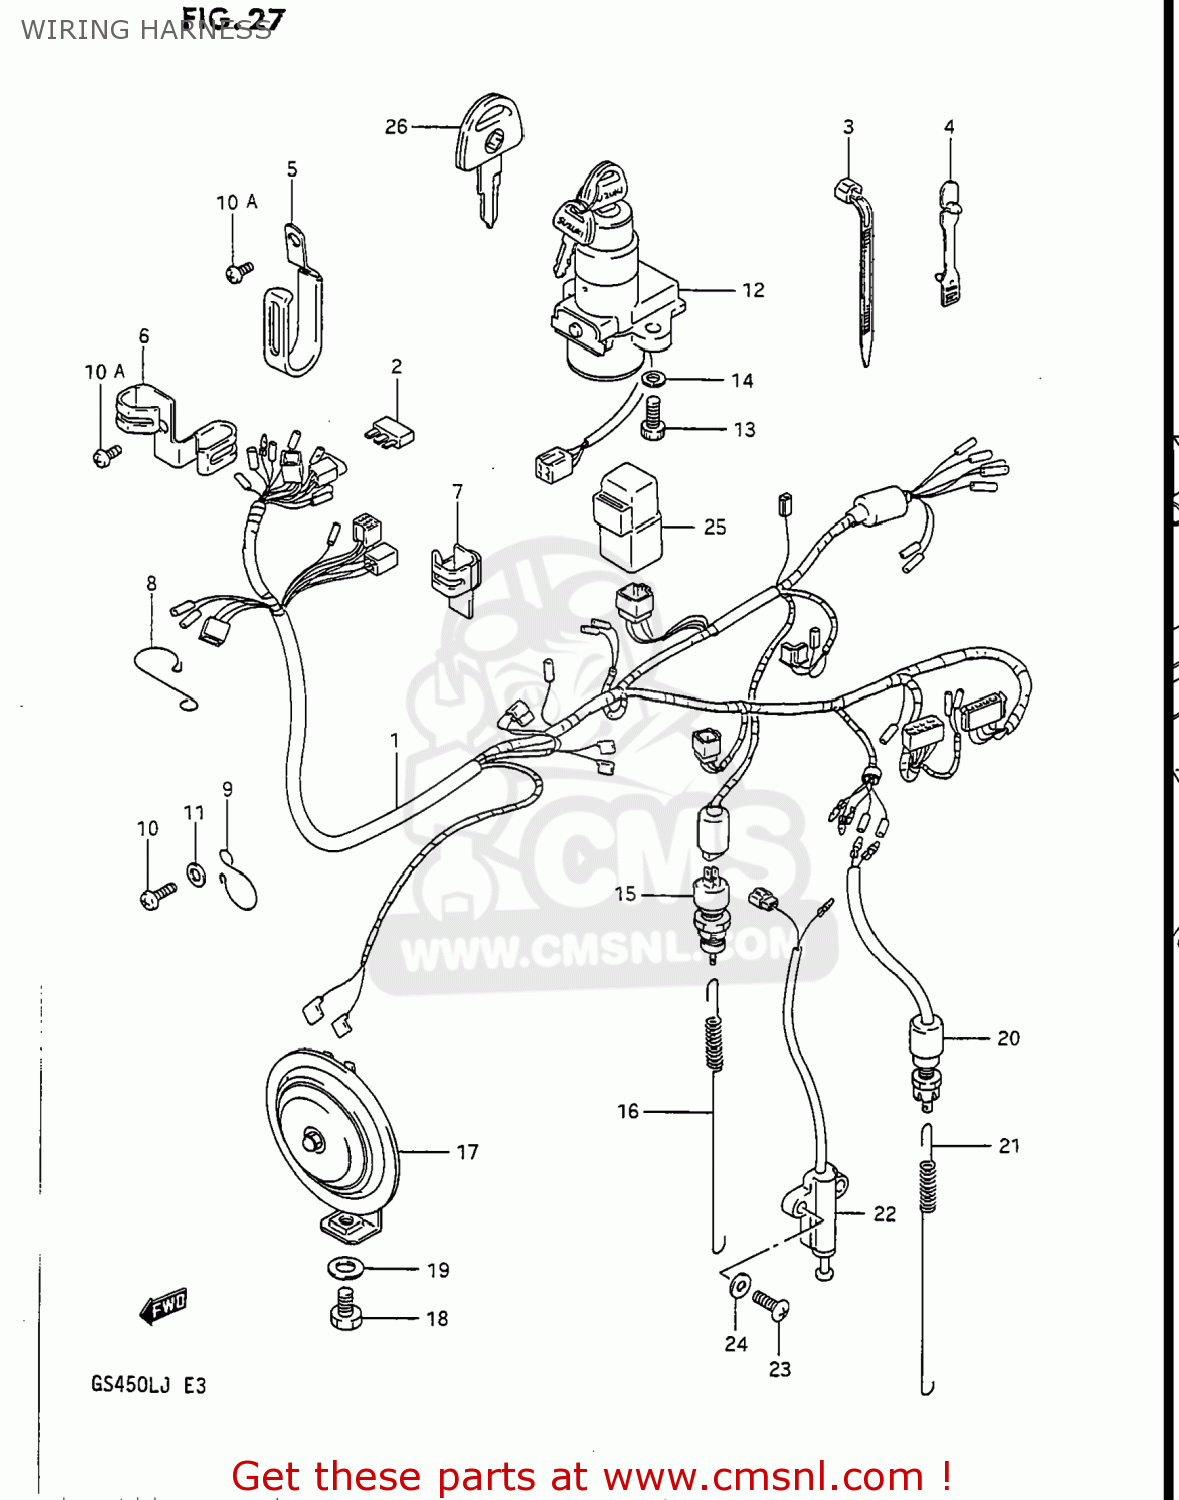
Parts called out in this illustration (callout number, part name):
1	HARNESS,WIRING
2	DIODE(STANLEY DE8804)
3	CLAMP(L:125)
4	CLAMP,L:88
5	CLAMP,WIRING HARNESS
6	CLAMP,WIRING HARNESS
7	CLAMP,WIRING HARNESS
8	CLIP,WIRING HARNESS
9	CLIP,WIRING HARNESS
10	SCREW
10A	SCREW
11	WASHER
12	SWITCH ASSY,IGNITION
13	BOLT
14	WASHER,LOCK
15	SWITCH ASSY,STOP LAMP
16	SPRING
17	HORN ASSEMBLY
18	BOLT
19	WASHER
20	SWITCH ASSEMBLY,SIDE STAND
21	SPRING
22	SWITCH ASSEMBLY,SIDE STAND
23	SCREW
24	WASHER
25	RELAY ASSEMBLY
26	KEY,BLANK
